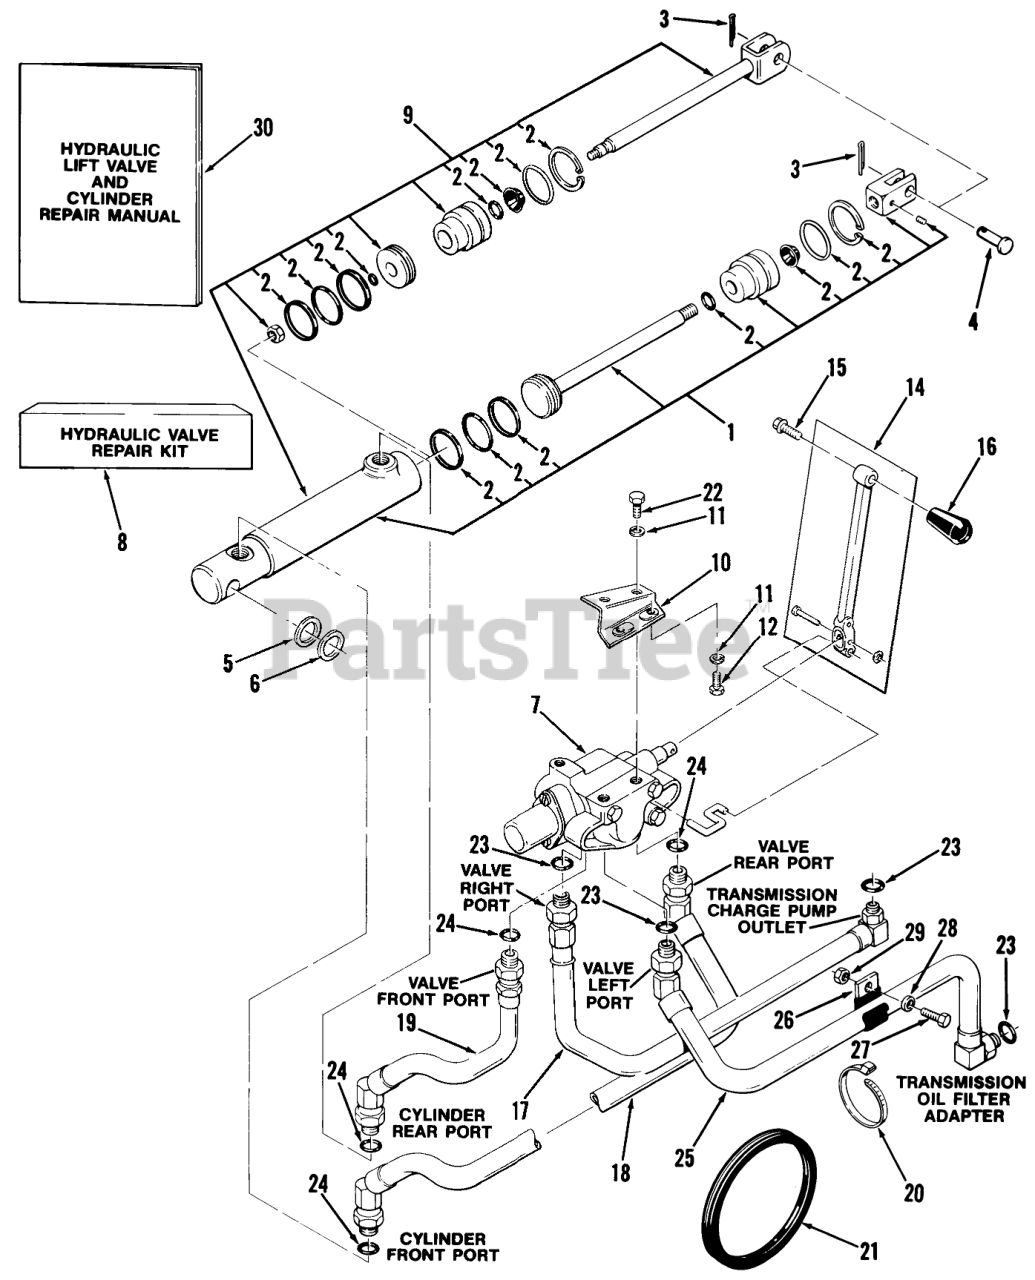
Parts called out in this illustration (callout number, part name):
1	Hydraulic Cylinder
2	S/A O-RING&GASKET AS
4	CLEVIS PIN
5	WASHER
6	Spacer
7	Hydraulic Valve
8	S.A. Repair Kit
9	CYLINDER
10	Mounting Bracket
11	Lockwasher
12	Bolt
14	S/A HANDLE&HARDWARE
15	SCREW
17	ASSY-HYDRAULIC HOSE
18	Hose-Valve To Cylinder
19	Hose-Valve To Cylinder
20	PLASTIC TIE
21	GROMMET
22	Bolt
23	0-Ring
24	O RING
25	ASSY-HYD HOSE
26	CLIP
27	H H C S
29	Nut
30	Repair Manual
